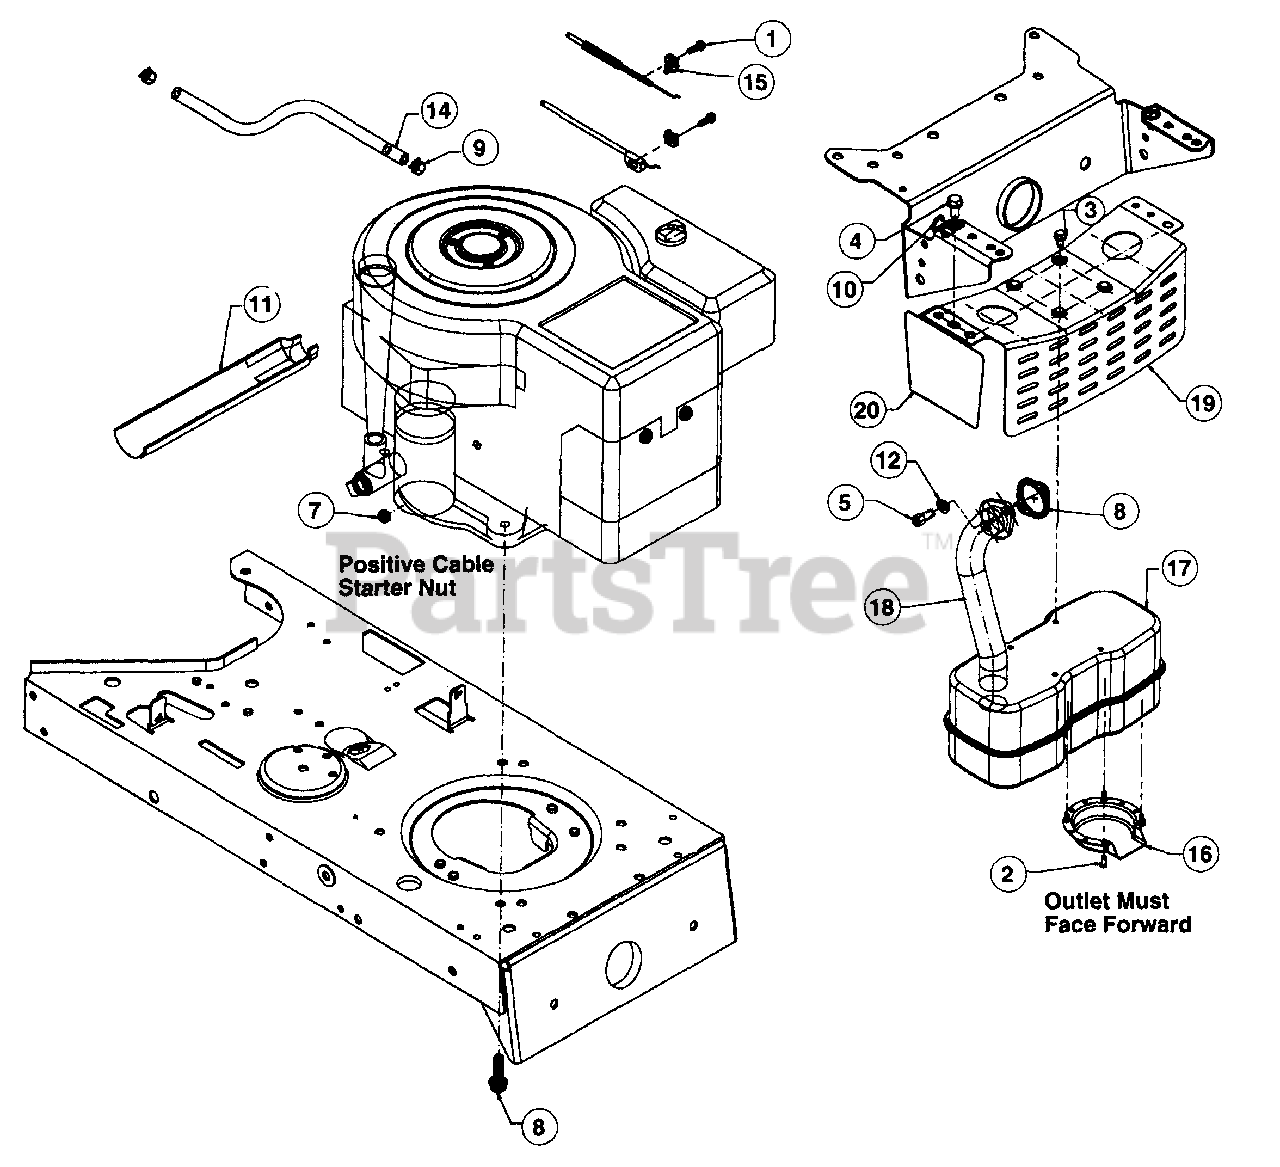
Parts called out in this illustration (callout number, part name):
1	Hex Wash. Scr. #10-32 x .62" Lg.
2	Hex Tap Scr. #8-32 x .38" Lg.
3	Hex Wash. TT-Tap Scr. 1/4-20 x .5" Lg.
4	Hex Wash. TT-Tap Scr. 5/16-18 x .62" Lg.
5	Socket Head Scr. 5/16-18 x .62" Lg.
7	Hex Sems Scr. 1/4-20 Thd.
8	Gasket
11	Oil Drain Sleeve
12	Lock Washer 5/16" I.D.
14	Fuel Line 12" Lg.
15	Casing Clamp
16	Muffler Deflector
17	Muffler
18	Exhaust Pipe
20	Shield Brkt.
